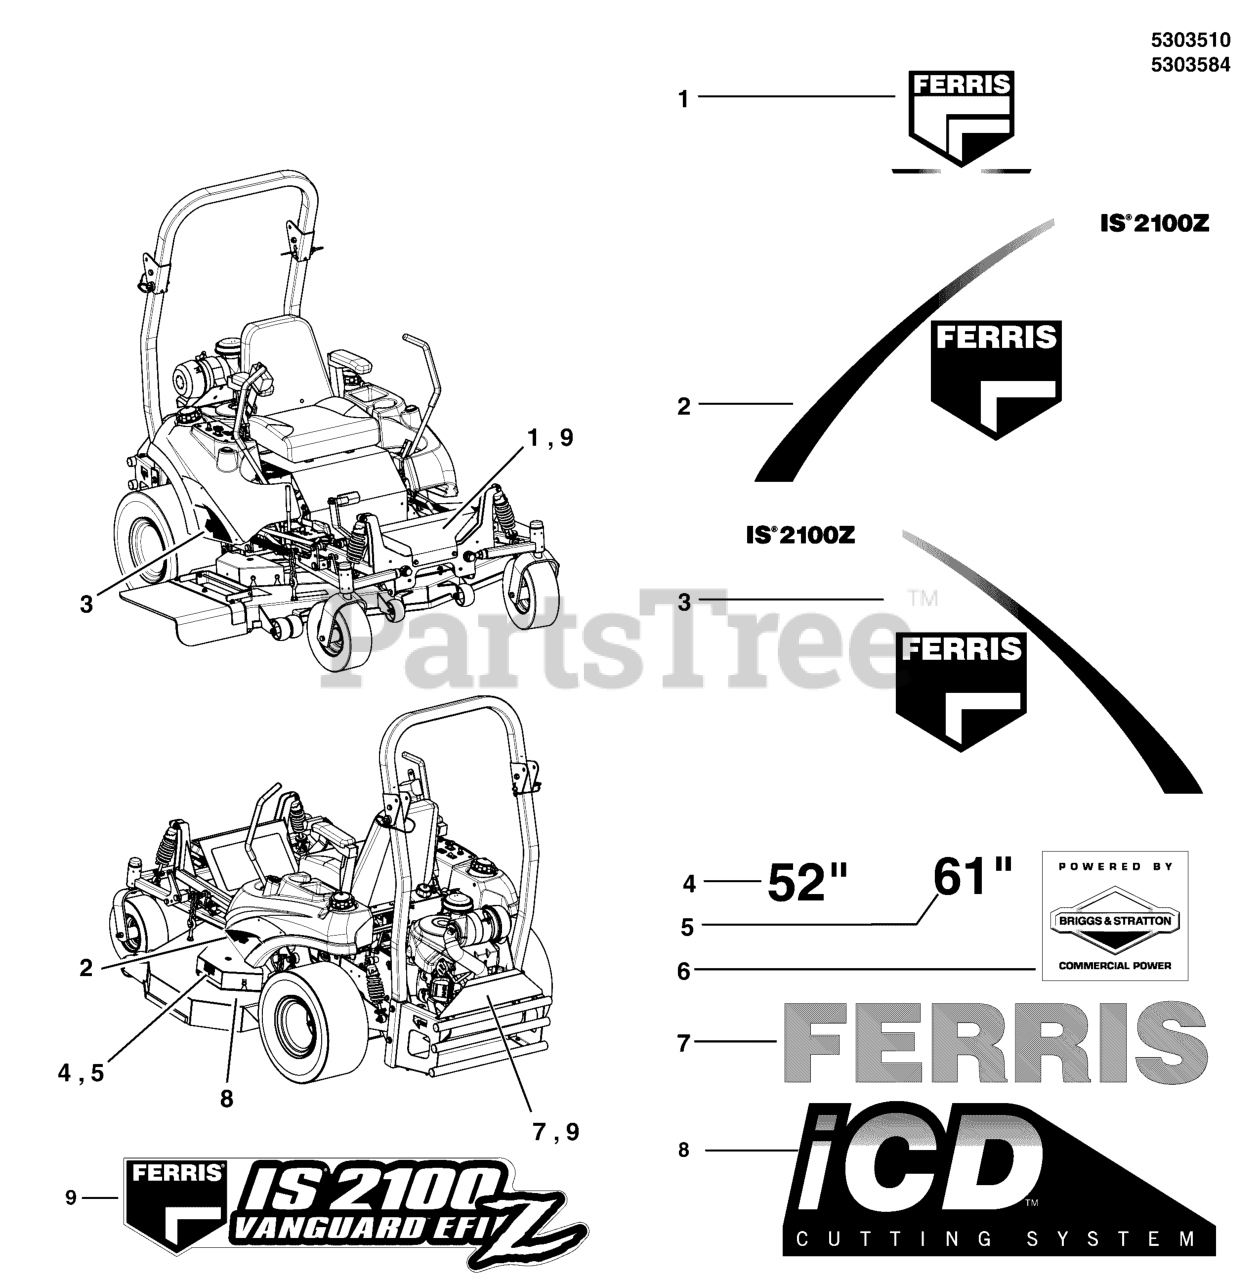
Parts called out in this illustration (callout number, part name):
1	DECAL, FERRIS, FRONT BADGE
2	DECAL, LH BADGE, IS2100
3	DECAL, RH BADGE, IS2100
4	DECAL, 52
5	DECAL, 61
7	DECAL, FERRIS, 2.23" X 11.39"
8	DECAL, iCD CUTTING SYSTEM
9	DECAL, LOGO, IS2100-EFI
